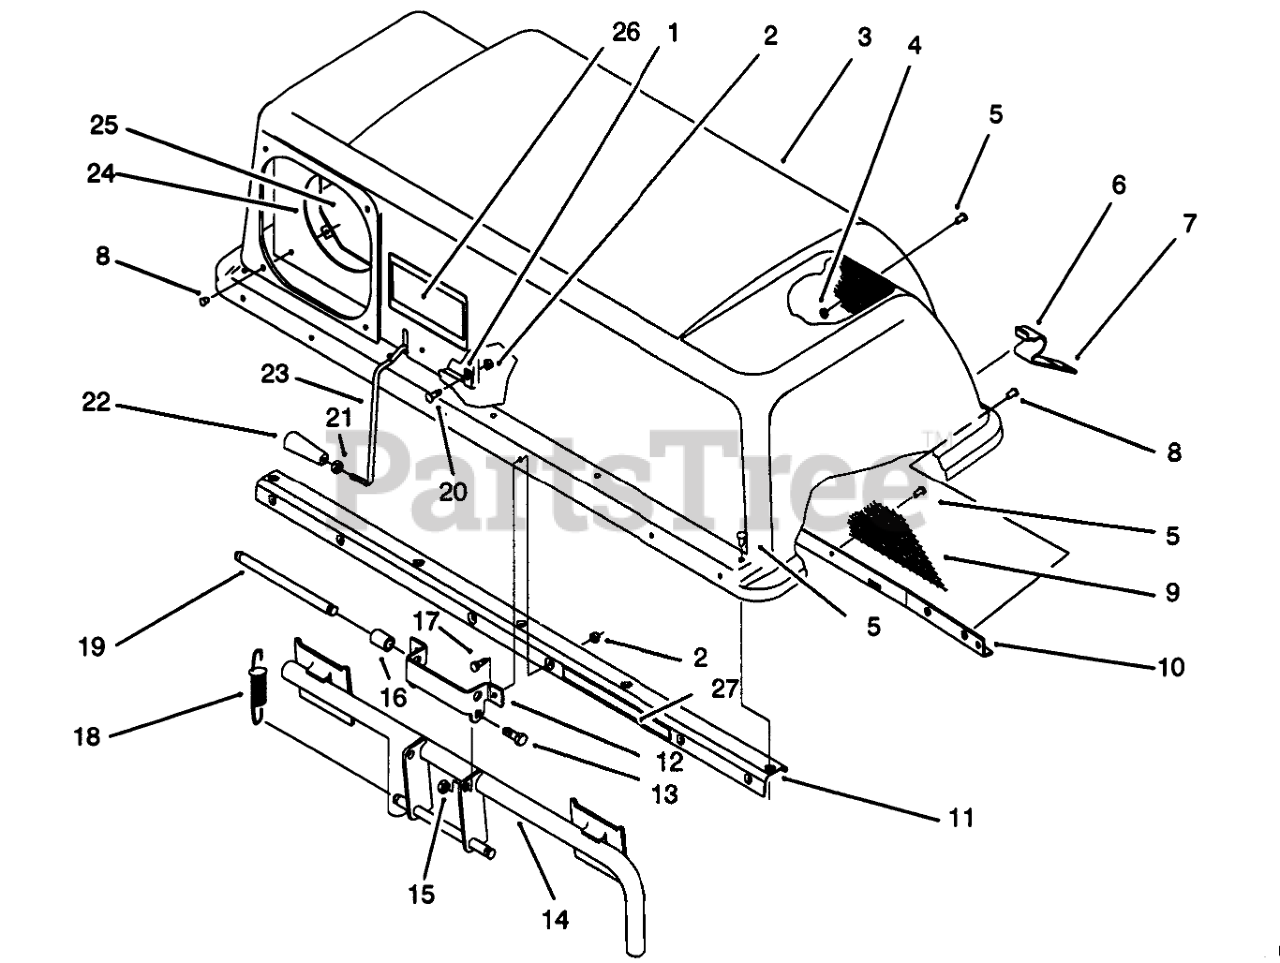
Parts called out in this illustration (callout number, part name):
1	Clip
2	NUT-LOCK, NI
3	TOP-BAGGER
4	Washer
5	RIVET-BLIND
6	Latch-Bag
8	Pop Rivet
9	SCREEN-BAGGER
10	SUPPORT-SCREEN B
11	Stiffener Assembly (Incl. Ref. #27)
12	HINGE-BAG TOPB
13	SCREW-HH
14	FRAME ASM
15	NUT-LOCK, NI
16	SPACER
17	SCREW-HH
18	SPRING-EXTENSION
19	PIN-SPRING
20	Screw
21	NUT-JAM
22	HANDLE-TAPERED
23	FEELER-FILL, BAG
24	SEAL-CHUTE
25	CLAMP-SEAL
26	DECAL
27	Decal
